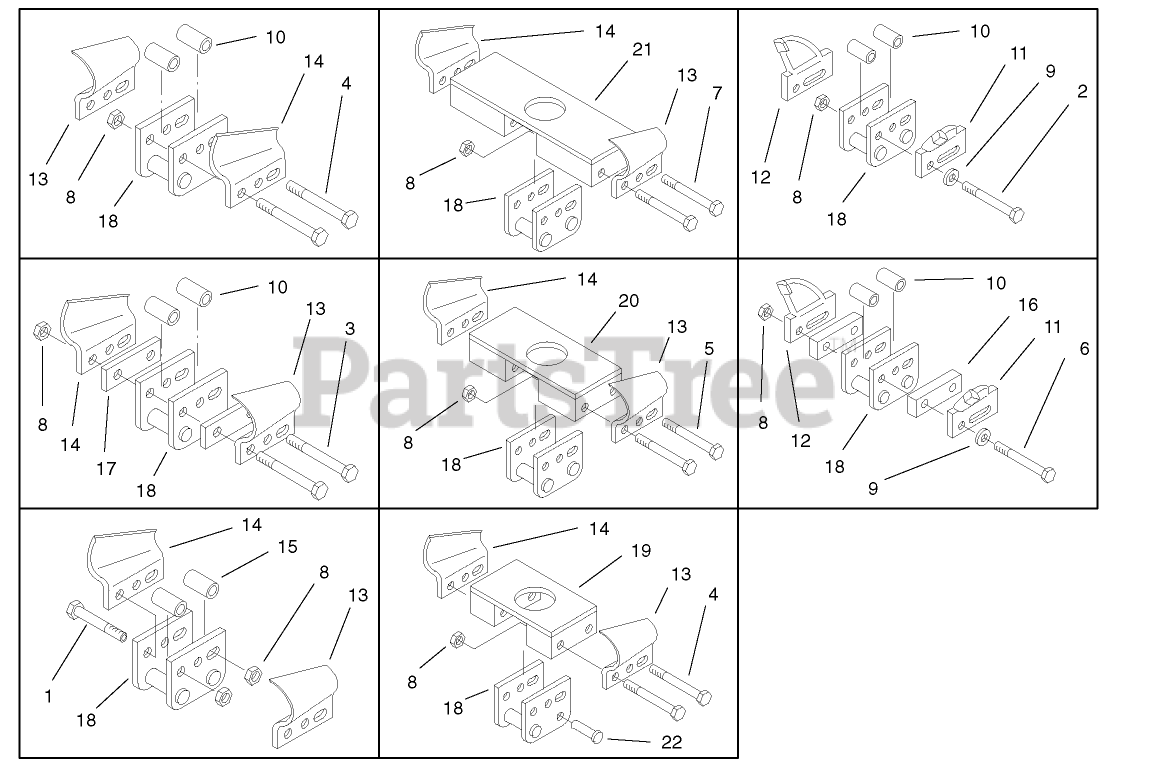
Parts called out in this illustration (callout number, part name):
1	SCREW-HH
2	SCREW-HH
3	SCREW-HH
4	SCREW-HH
5	SCREW-HH
6	SCREW-HH
7	SCREW-HH
8	Nut
9	WASHER-FLAT
10	SPACER-TUBE
11	TOOTH- ROCK, LH
12	TOOTH-ROCK, RH
13	TOOTH-SOIL, LH
14	TOOTH-SOIL, RH
15	SPACER-TUBE
16	SPACER-CUT, 6 INCH
17	SPACER-CUT, 5 INCH
18	CHAIN-BARE, 32 STATION
18	CHAIN-BARE, 24 STATION
19	ADAPTER-8 Inch
20	ADAPTER-10 Inch
21	ADAPTER-12 Inch
22	PIN-CONNECTING
